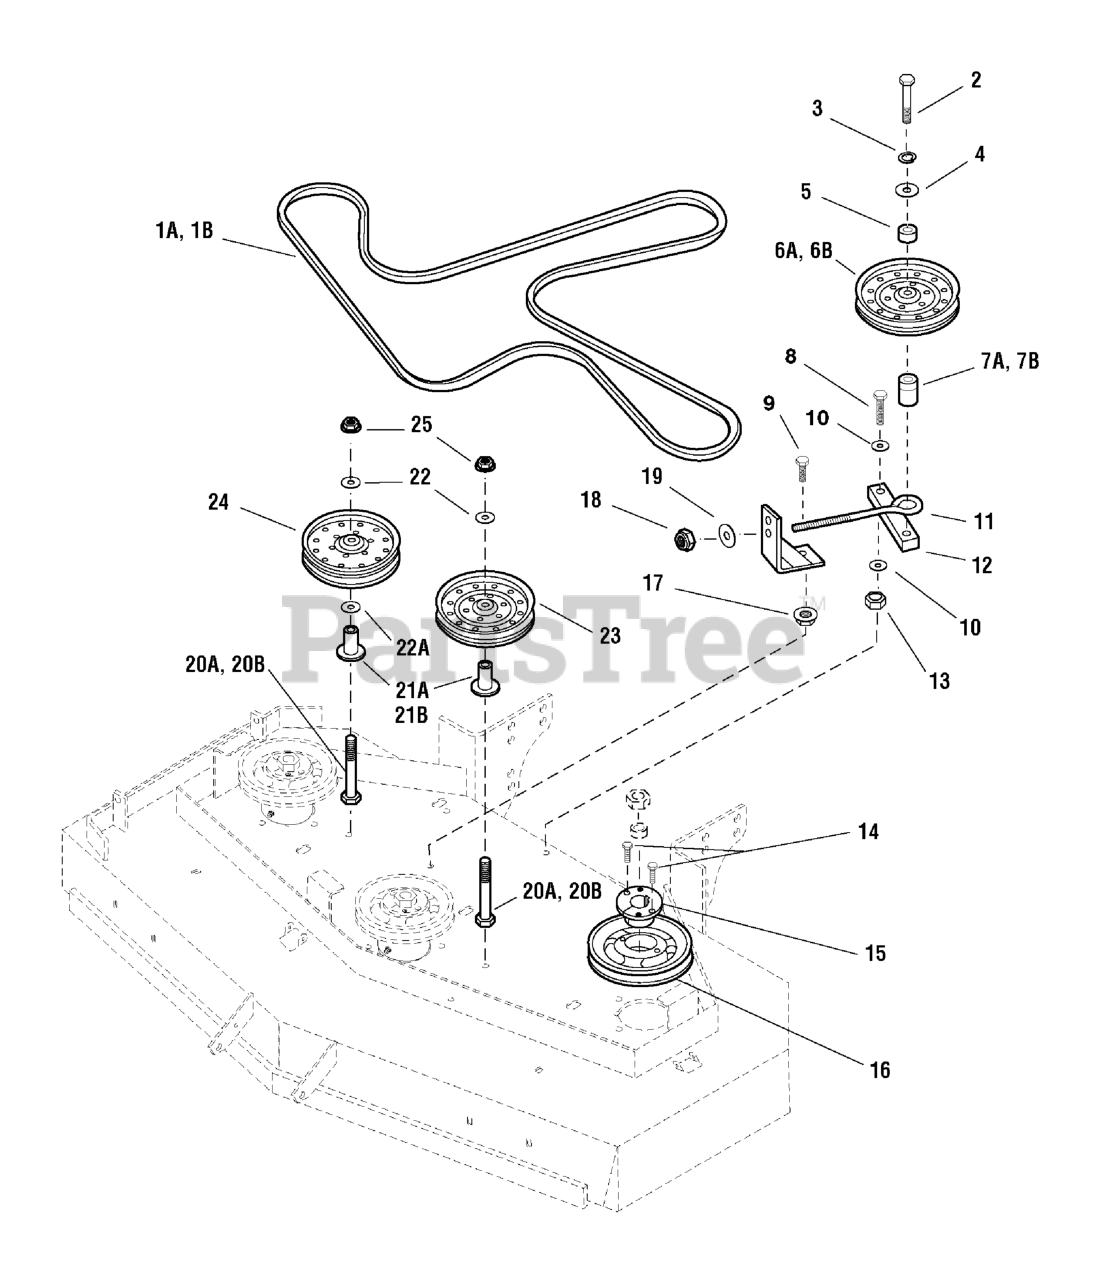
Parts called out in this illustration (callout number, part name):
1A	BELT, BP-SEC, 130.97EL, LRG ARAMID, WRPD
1B	BELT, Blade Spindle
2	BOLT, 1/2-20 X 4" GD5 YZ
3	WASHER, 1/2" SPLIT LOCK
4	WASHER, 1/2 SAE
5	SPACER, .52 X 1.00 X .75, CZ
6A	PULLEY, Backside Idler
7A	SPACER, .52 X 1.00 X .88, PM, CZ
7B	SPACER, .52 x 1.00 x 1.75
8	BOLT, 7/16-20 X 1-3/4" GD.5
9	BOLT, 3/8-16 X 1" GD5 CZ
10	WASHER, 7/16" SAE
11	EYE BOLT, 3/8-16 X 8, 3THRD, 1EYE, CZ
12	ARM, Idler
13	NUT, 7/16-20 Hex Nylon Lock
14	BOLT, 1/4-20 X 1-1/4 GD5 CZ
15	BUSHING, Tapered Hub
16	PULLEY, Spindle
17	NUT, 3/8-16 Hex Large Serrated Flange
18	NUT, 3/8-16 HEX NYLON LOCK
19	WASHER, 3/8 SAE
20A	BOLT, 1/2-13 X 4" GD5 CZ
20B	BOLT, 1/2-13 X 5" GD5 YZ
21A	MOUNT, Idler
21B	MOUNT, Idler
22	WASHER, 1/2 SAE
22A	WASHER, 1/2 SAE
23	PULLEY, Backside Idler
24	PULLEY, Idler
25	NUT, 1/2-13 HEX NYLON LOCK
